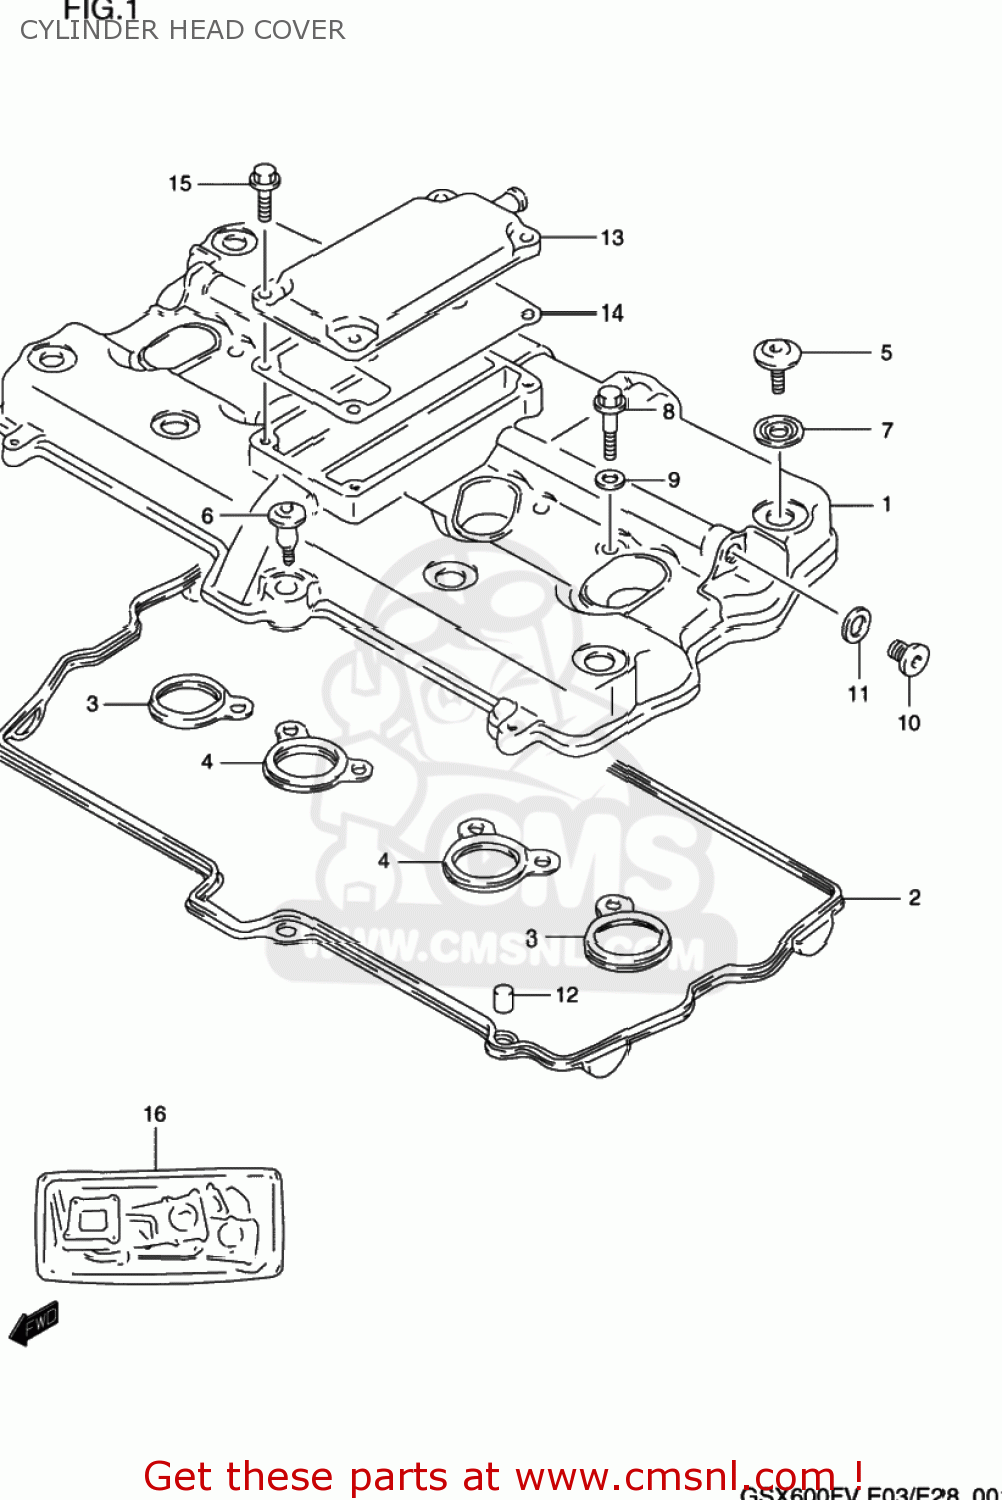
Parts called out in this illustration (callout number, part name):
1	COVER,CYLINDER HEAD
2	GASKET,CYLINDER HEAD COVER (NAS)
3	GASKET,HEAD COVER NO.2 (NAS)
4	GASKET,HEAD COVER NO.3 (NAS)
5	BOLT(7X17.5)
6	BOLT(7X31)
7	WASHER(10.6X25.5X2.3)
8	BOLT,UNION 8X35
9	GASKET 8.2X14X1 (NAS)
10	PLUG(L:12)
11	GASKET(12.1X16.2X3.7) (NAS)
12	PIN
13	COVER,BREATHER
14	GASKET,BREATHER COVER (NAS)
15	BOLT
16	GASKET SET (NAS)
